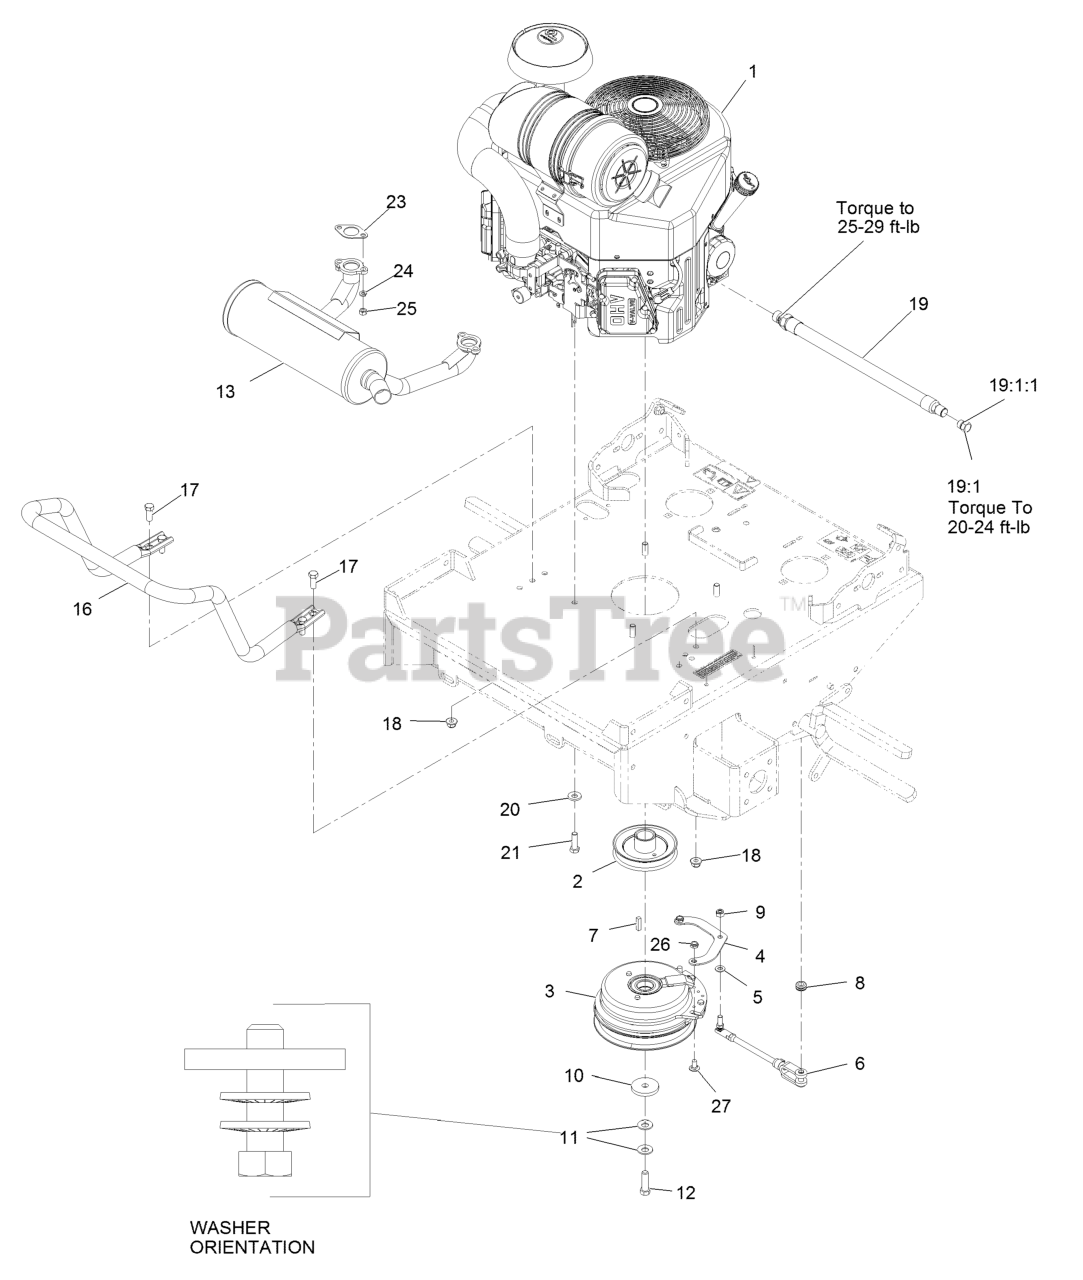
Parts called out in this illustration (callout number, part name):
2	SHEAVE W/ HUB
3	CLUTCH, 200 FT/LBS, 1.13
4	STRAP, CLUTCH
5	WASHER-PLAIN
6	ASM, CLUTCH ANCHOR
7	KEY
8	GROMMET
9	NUT-LOCK
10	WASHER-CLUTCH
11	WASHER-SPRING
12	BOLT-HEX, TAP
13	MUFFLER,HORIZONTAL
16	GUARD-MUFFLER
17	SCREW-HH
18	NUT-HF, NI
19	ASM, ENGINE OIL DRAIN HOS
19:1	PLUG-HH
19:1:1	O-RING
20	WASHER-BELLEVILLE
21	SCREW-HH
23	GASKET-EXHAUST
24	WASHER-LOCK
26	NUT-LOCK, NI
27	SCREW-CARR
